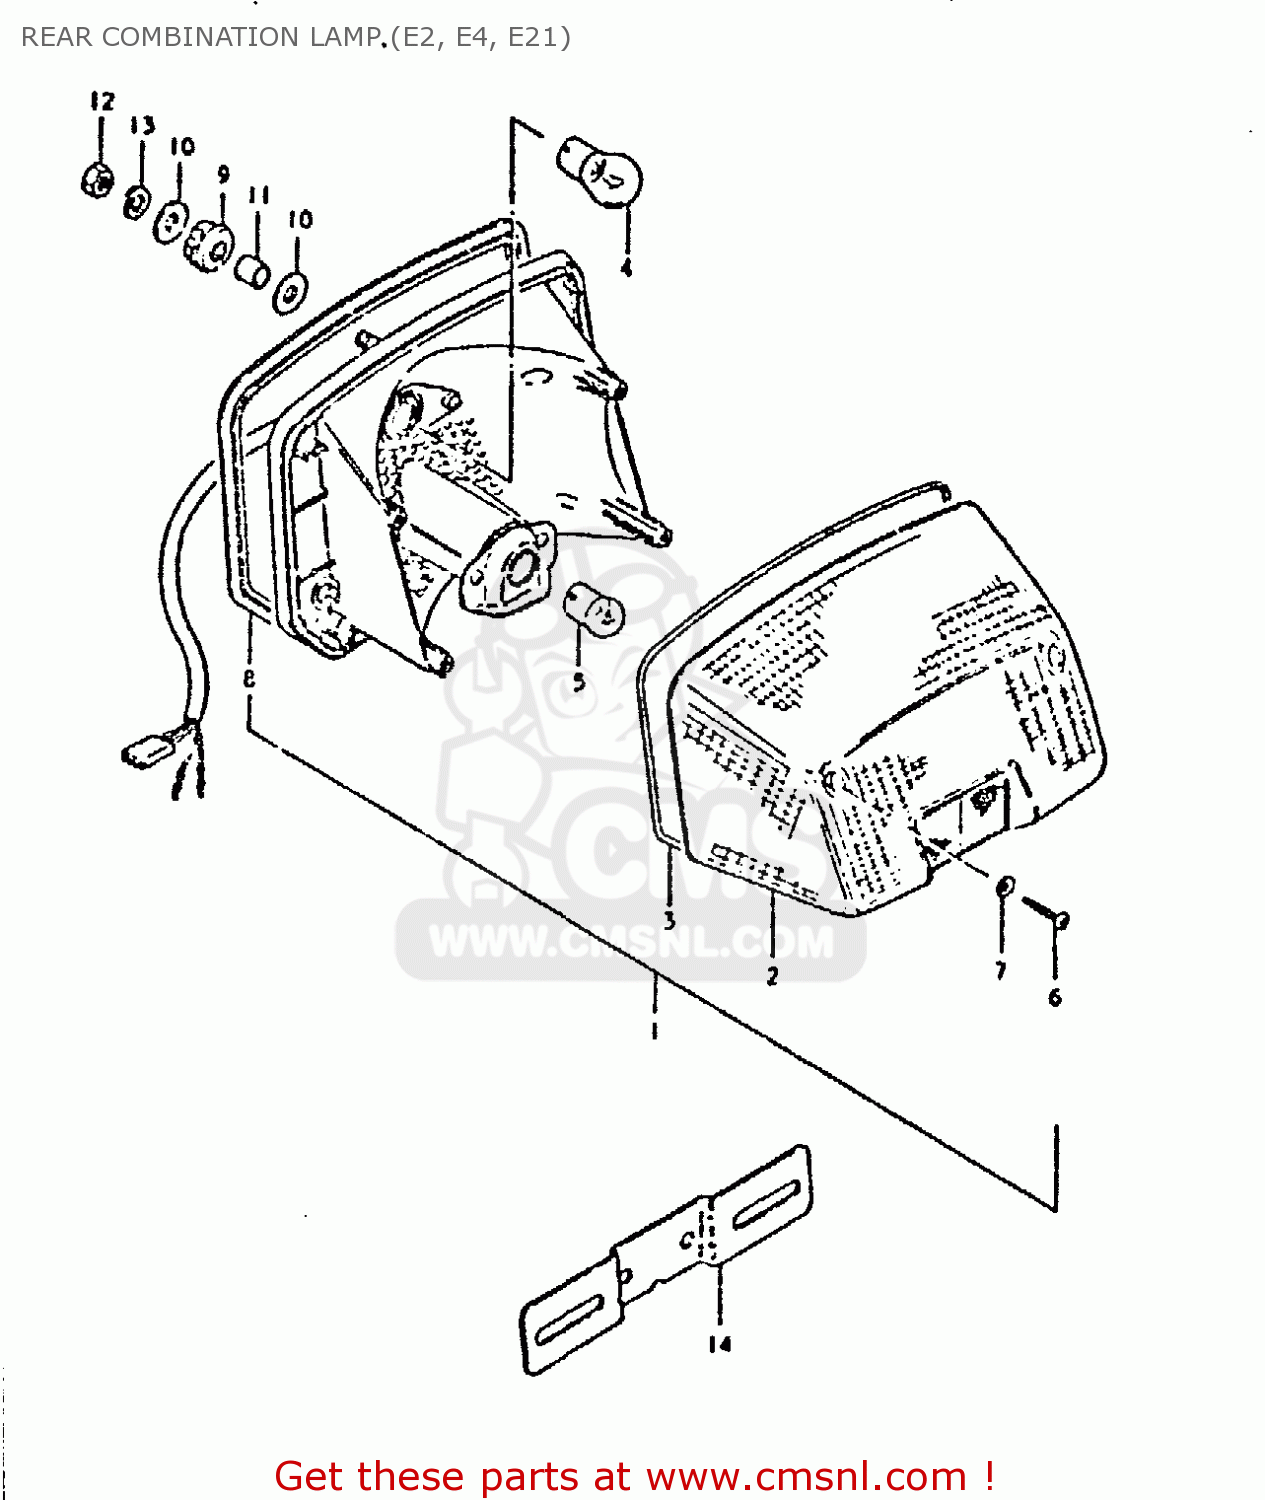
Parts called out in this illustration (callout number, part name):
1	LAMP ASSY, TAIL
2	LENS
3	GASKET (NAS)
4	BULB 12V21/5W
5	BULB
6	SCREW
7	GASKET (NAS)
8	GASKET,REAR COMBINATION LAMP
9	CUSHION
10	WASHER
11	SPACER (6.8X10X11.5)
12	NUT
13	LOCK WASHER
14	PLATE, LICENSE
